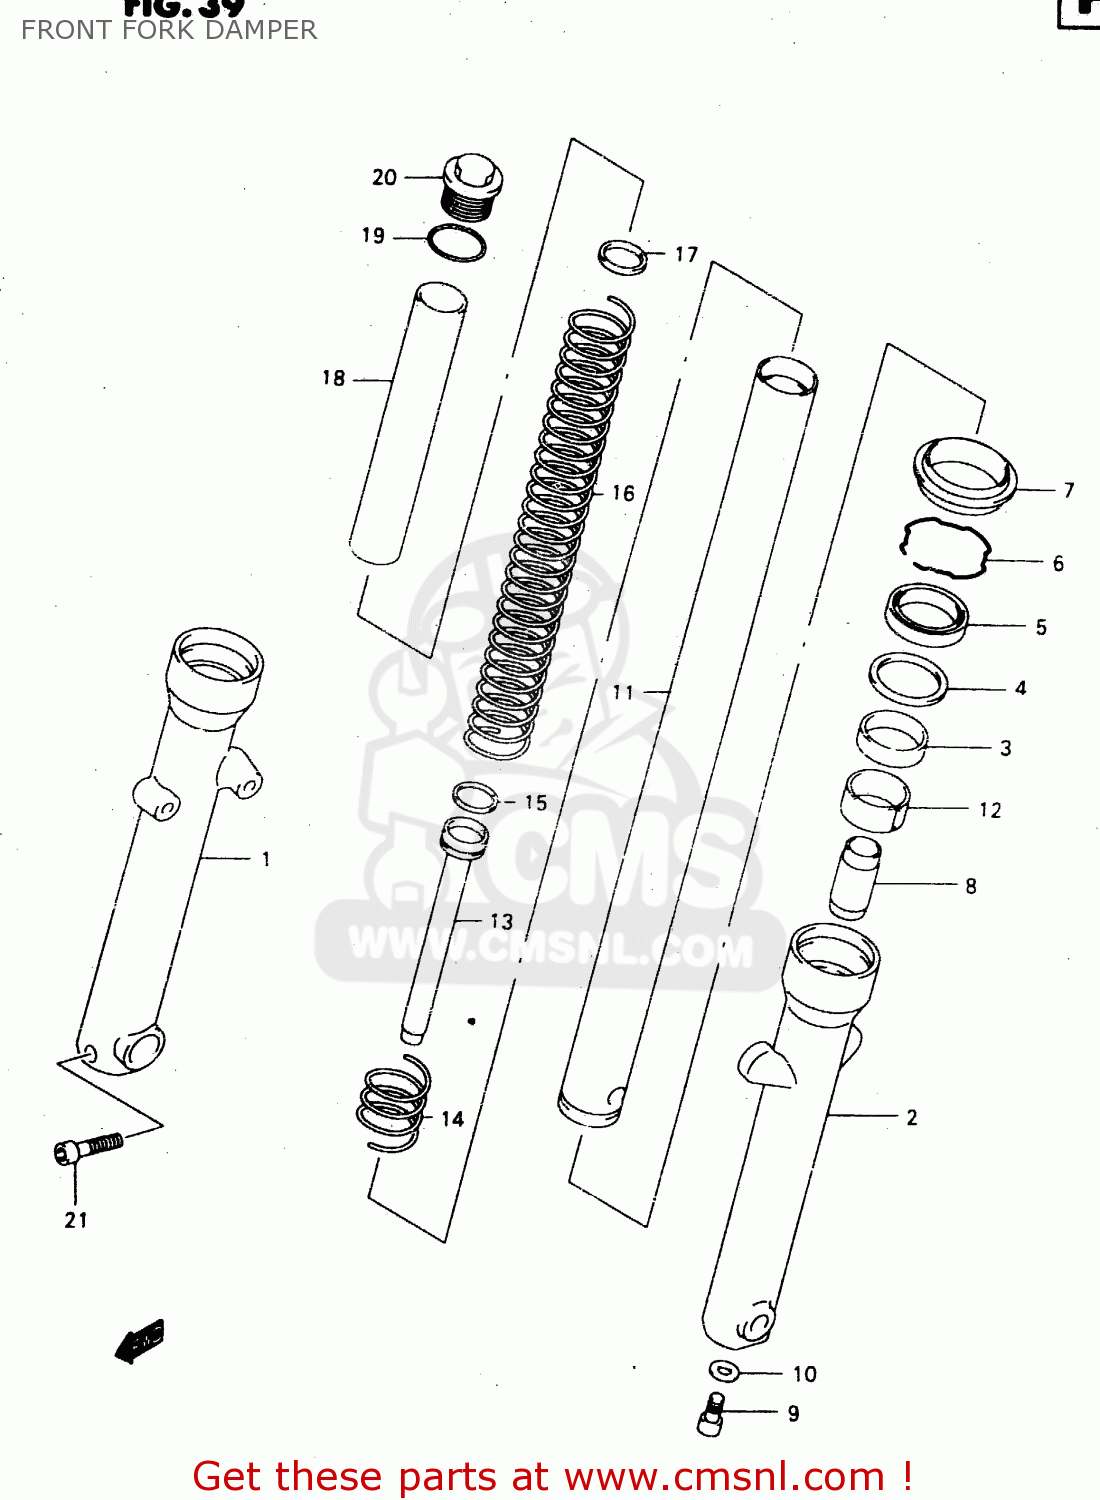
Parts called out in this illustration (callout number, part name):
1	TUBE,OUTER,R
2	TUBE,OUTER,L
3	BUSHING,GUIDE
4	SPACER,SEAL
5	OIL SEAL,FRONT FORK
6	RING,STOPPER
7	SEAL,DUST
8	PIECE,OIL LOCK
9	BOLT,CENTER (8X18)
10	GASKET (NAS)
11	TUBE,INNER
12	BUSHING,SLIDE
13	PIPE,SEAT
14	SPRING,REBOUND
15	RING,PISTON
16	SPRING,FR
17	JOINT,SPRING
18	SPACER,SPRING
19	O RING
20	BOLT,FR FORK
21	BOLT
